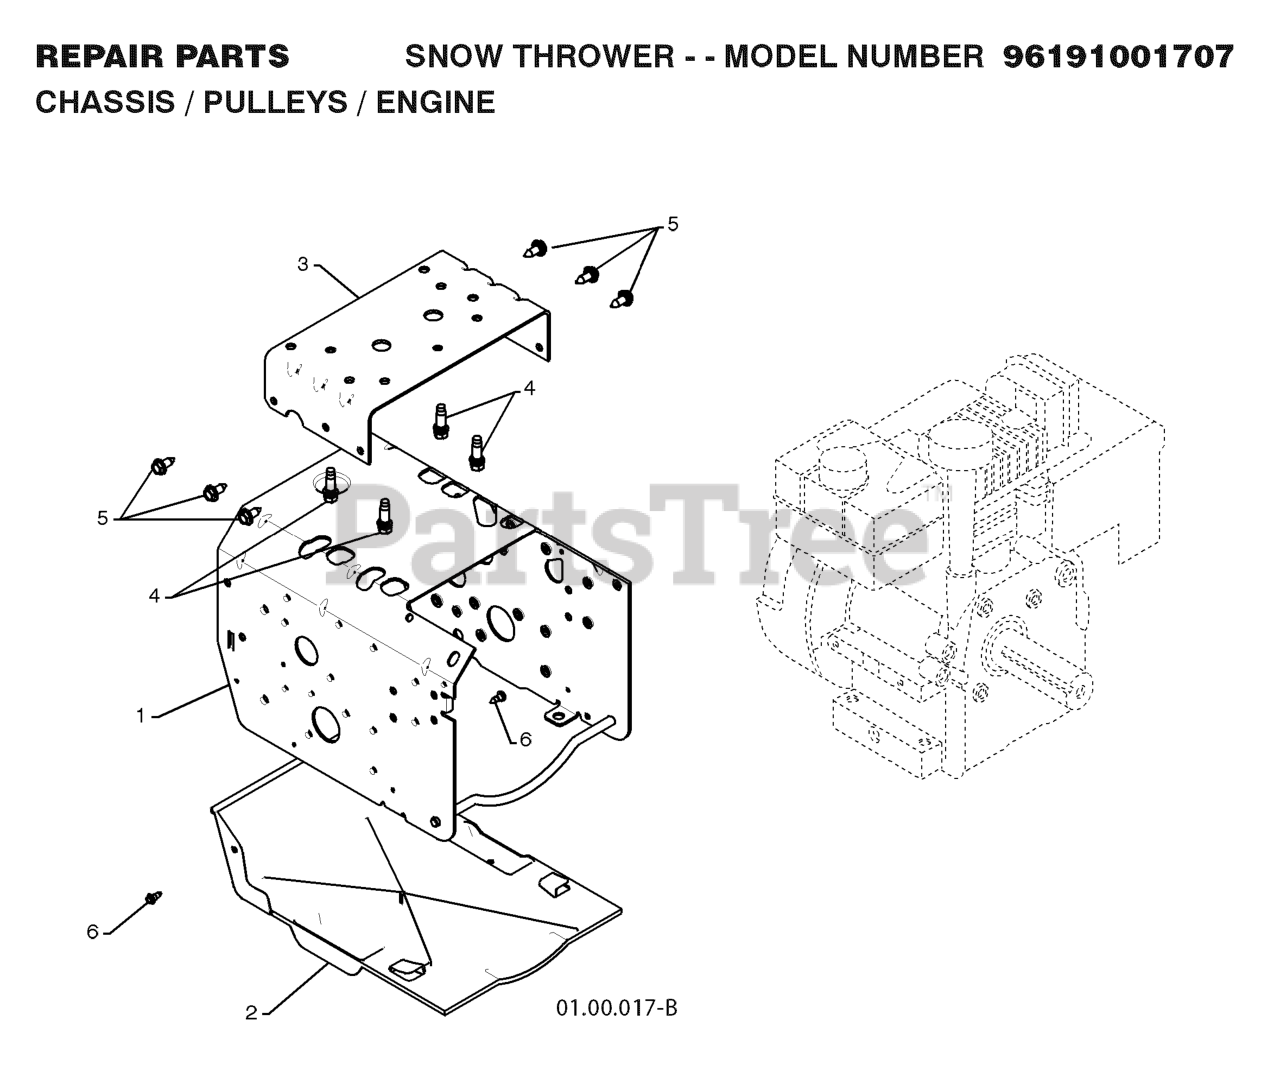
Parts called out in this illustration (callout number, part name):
1	FRAME.WELD.PNT.003BGP
2	PAN.BOTTOM.PLASTIC
3	PLATE.ENGINE.MOUNT.ORANGE
4	BOLT 3/8-16X1-1/8
5	SELF-TAPPING SCREW 5/16-18X3/4
6	SCREW, HEX HEAD, TAPPING
